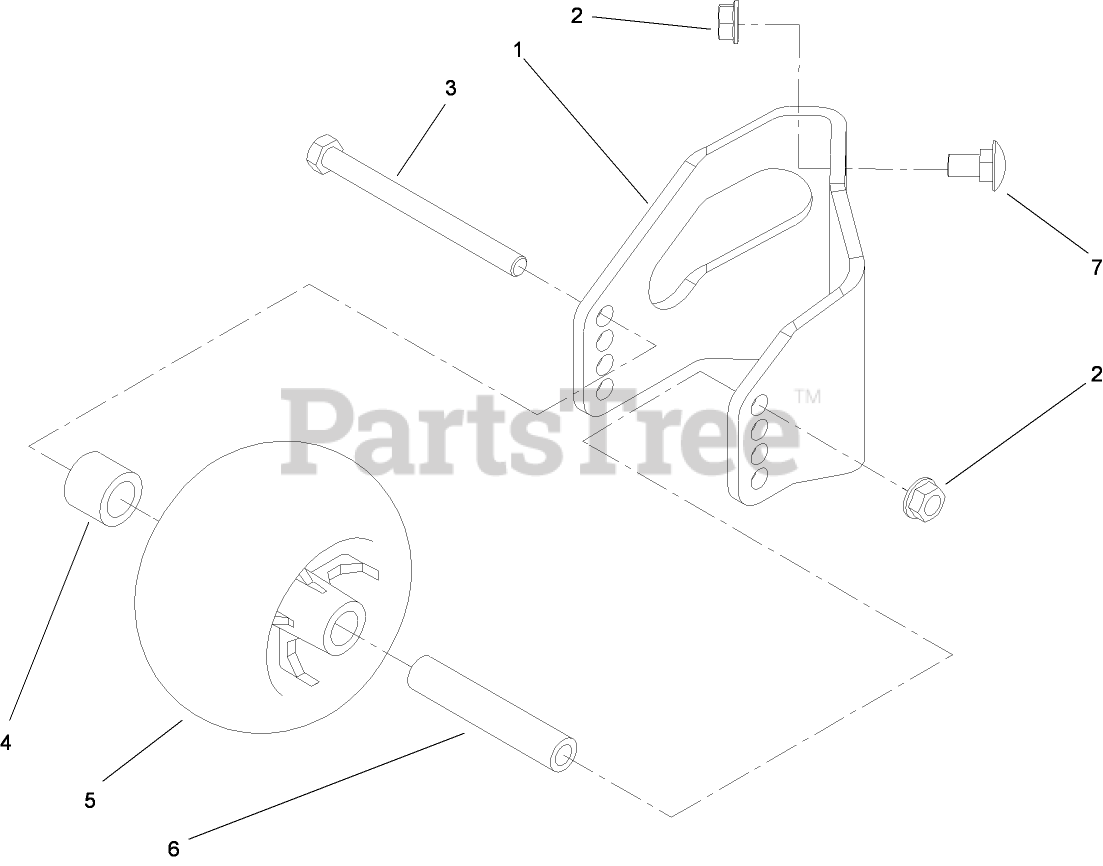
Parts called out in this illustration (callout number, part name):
1	BRACKET-ROLLER, LH
2	NUT-HHF, WHIZ
3	SCREW-HH
4	TUBE-SPACER
5	ROLLER-SCALP, ANTI
6	TUBE-SPANNER
7	SCREW-CARR
